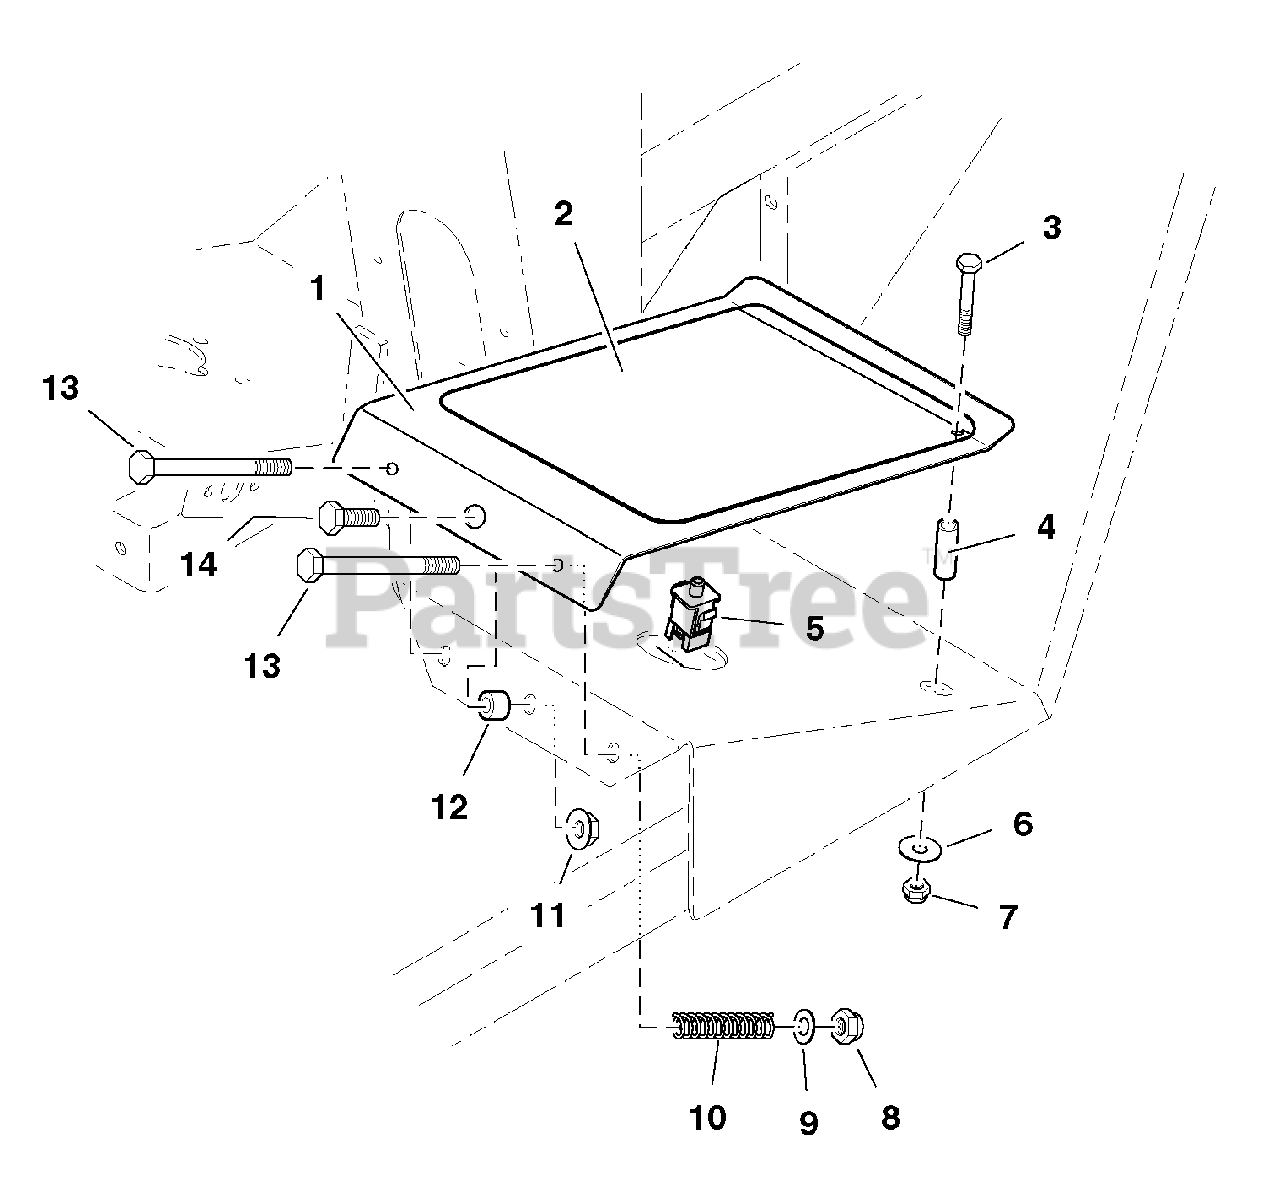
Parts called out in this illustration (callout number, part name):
1	OPERATOR PRESENCE PLATE
2	SAFETY WALK
3	CAPSCREW, Hex Hd, 5/16-18 x 2
4	BUSHING
5	SWITCH, Plunger, Snap-In, NO/NO
6	WASHER, Fender ,5/16
7	NUT, Hex, Nylon Lock, 5/16-18
8	NUT, Hex, Nylon Lock, 3/8-16
9	WASHER, 3/8
10	SPRING, Compression
11	NUT, Hex, Serrated Flange, 3/8-16
13	CAPSCREW, Hex Hd, 3/8-16 x 3-1/2
14	CAPSCREW, Hex Hd, 3/8-16 x 1
